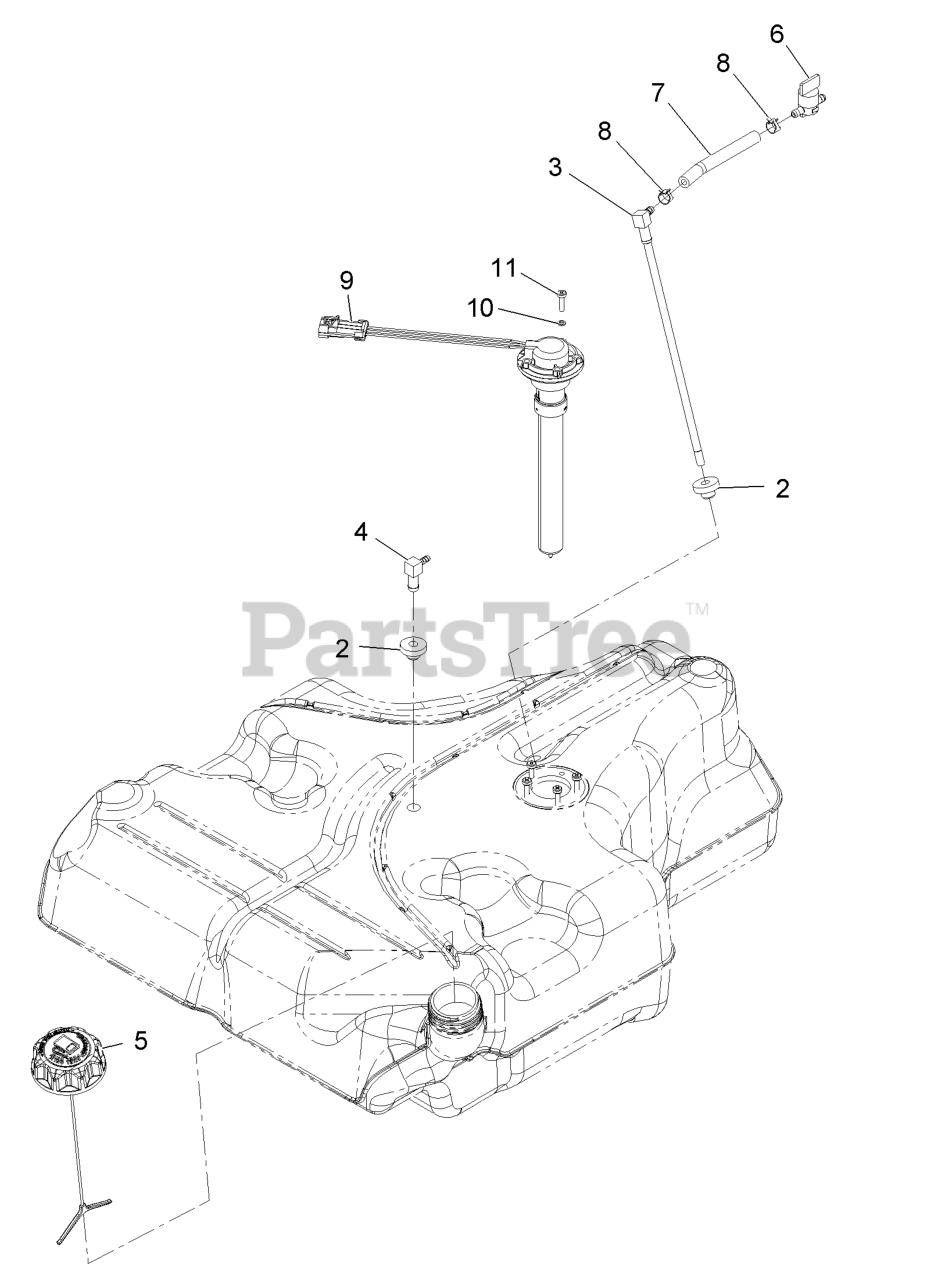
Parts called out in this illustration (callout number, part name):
2	BUSHING
3	FUEL LINE KIT (WITH GROMMET)
4	FITTING-90 ELBOW
6	VALVE-FUEL
7	HOSE-FUEL
8	CLAMP-HOSE
10	WASHER-LOCK
11	SCREW-PAN
